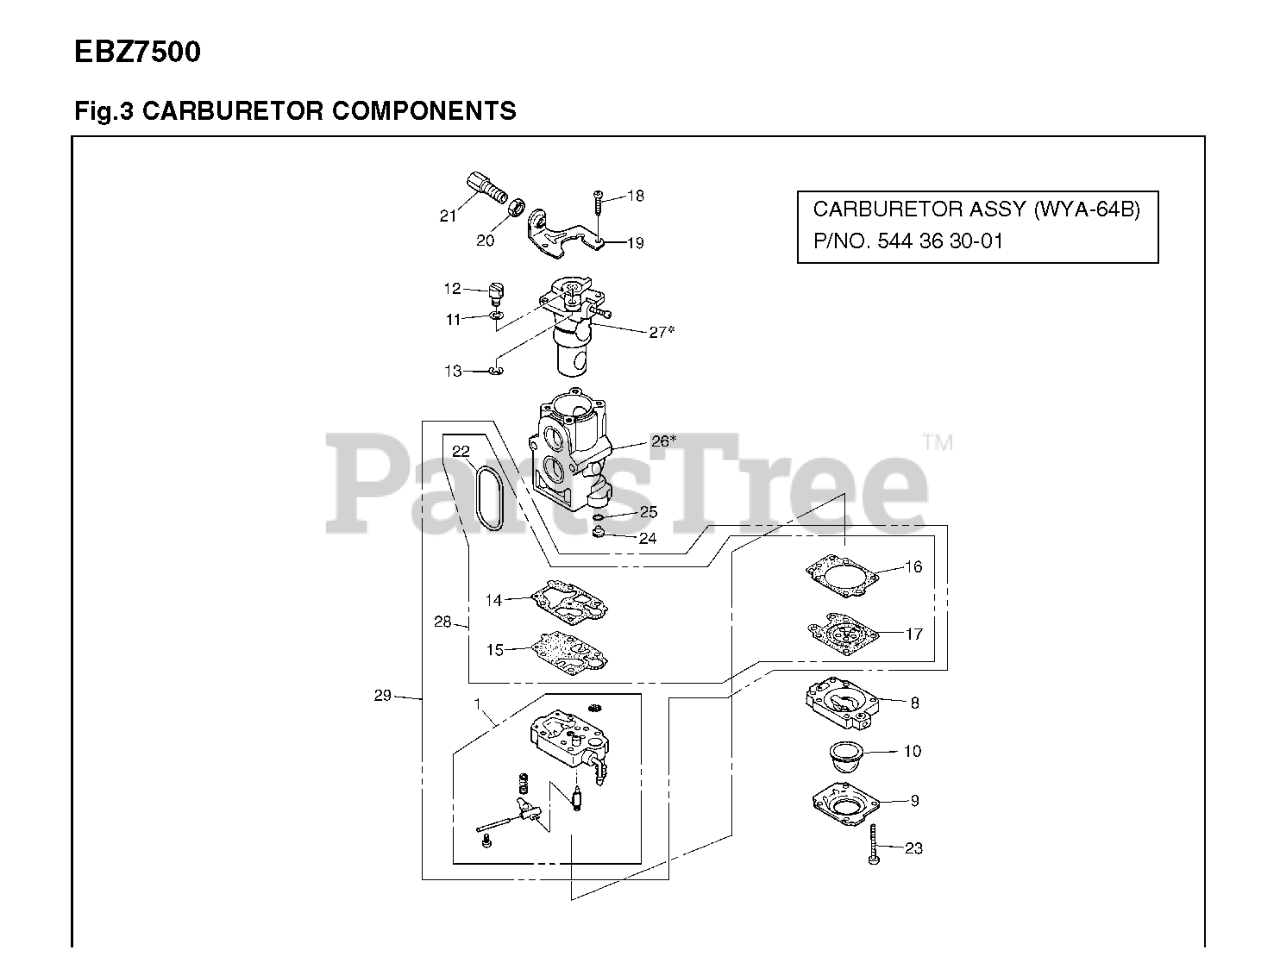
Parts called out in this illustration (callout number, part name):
1	BODY-A-PUMP
9	1OVER
11	WASHER
12	SWIVEL
13	RING
15	DIAPHRAGM
17	DIAPHRAGM
18	SCREW
19	BRACKET
20	NUT
21	ADJUSTER
22	RING
24	JET #58
26	CARB
27	CARB
28	GASKET KIT
29	REBUILD KIT
544363001	CARB
